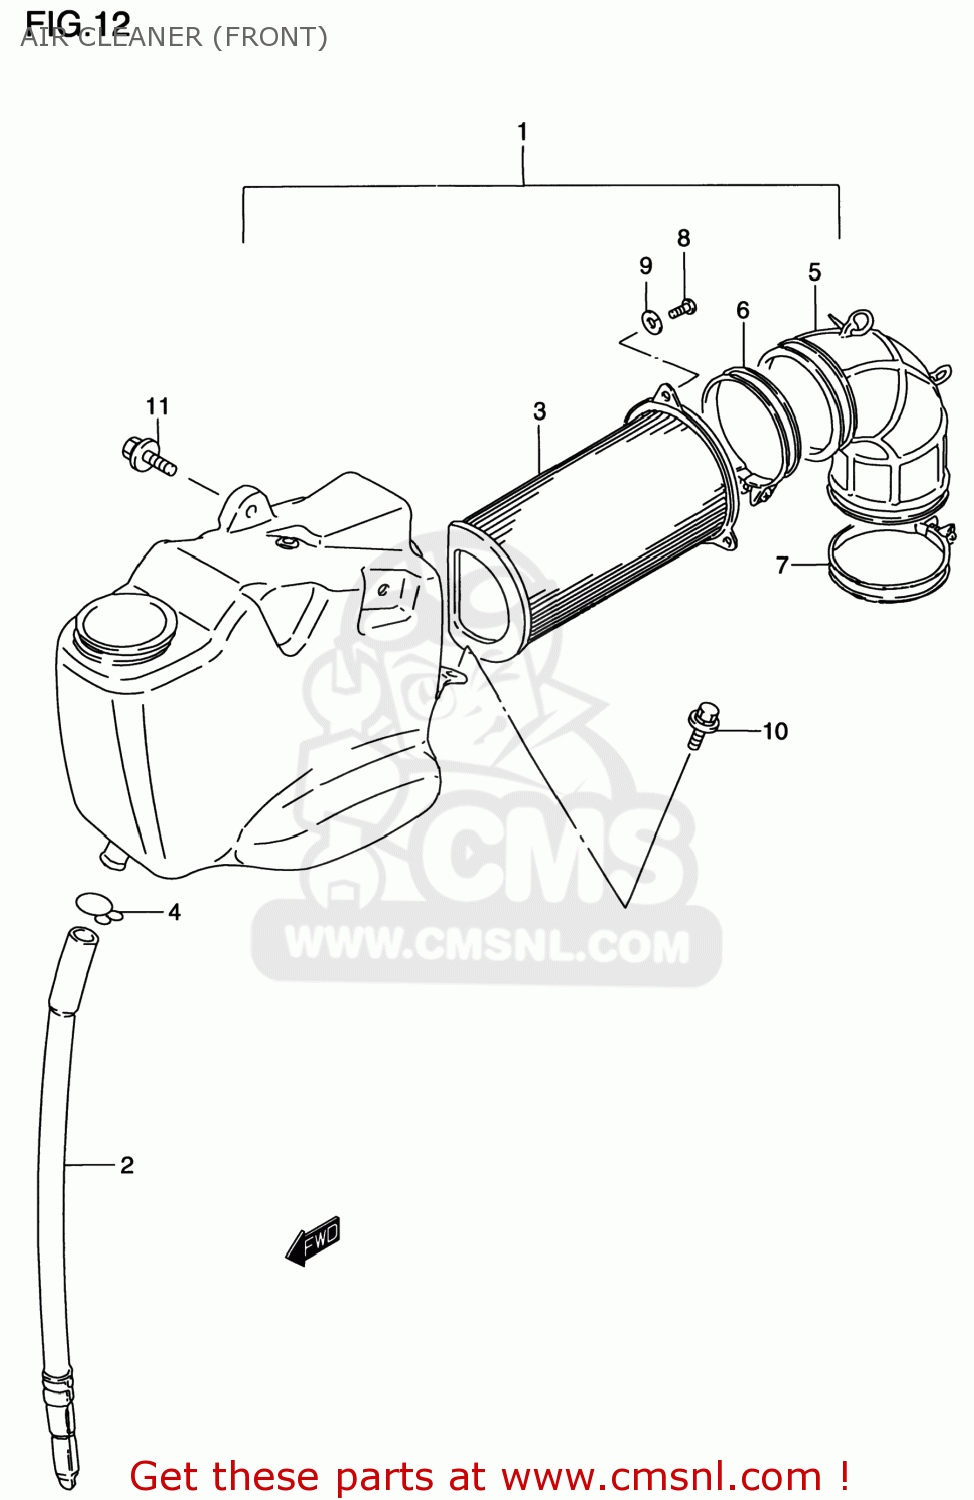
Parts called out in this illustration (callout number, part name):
1	CLEANER ASSY,AIR FR
2	TUBE,DRAIN
3	FILTER ASSY
4	CLIP
5	TUBE,AIR CLEANER OUTLET
6	CLAMP
7	CLAMP
8	SCREW
9	WASHER,LOCK
10	BOLT
11	BOLT, REAR
